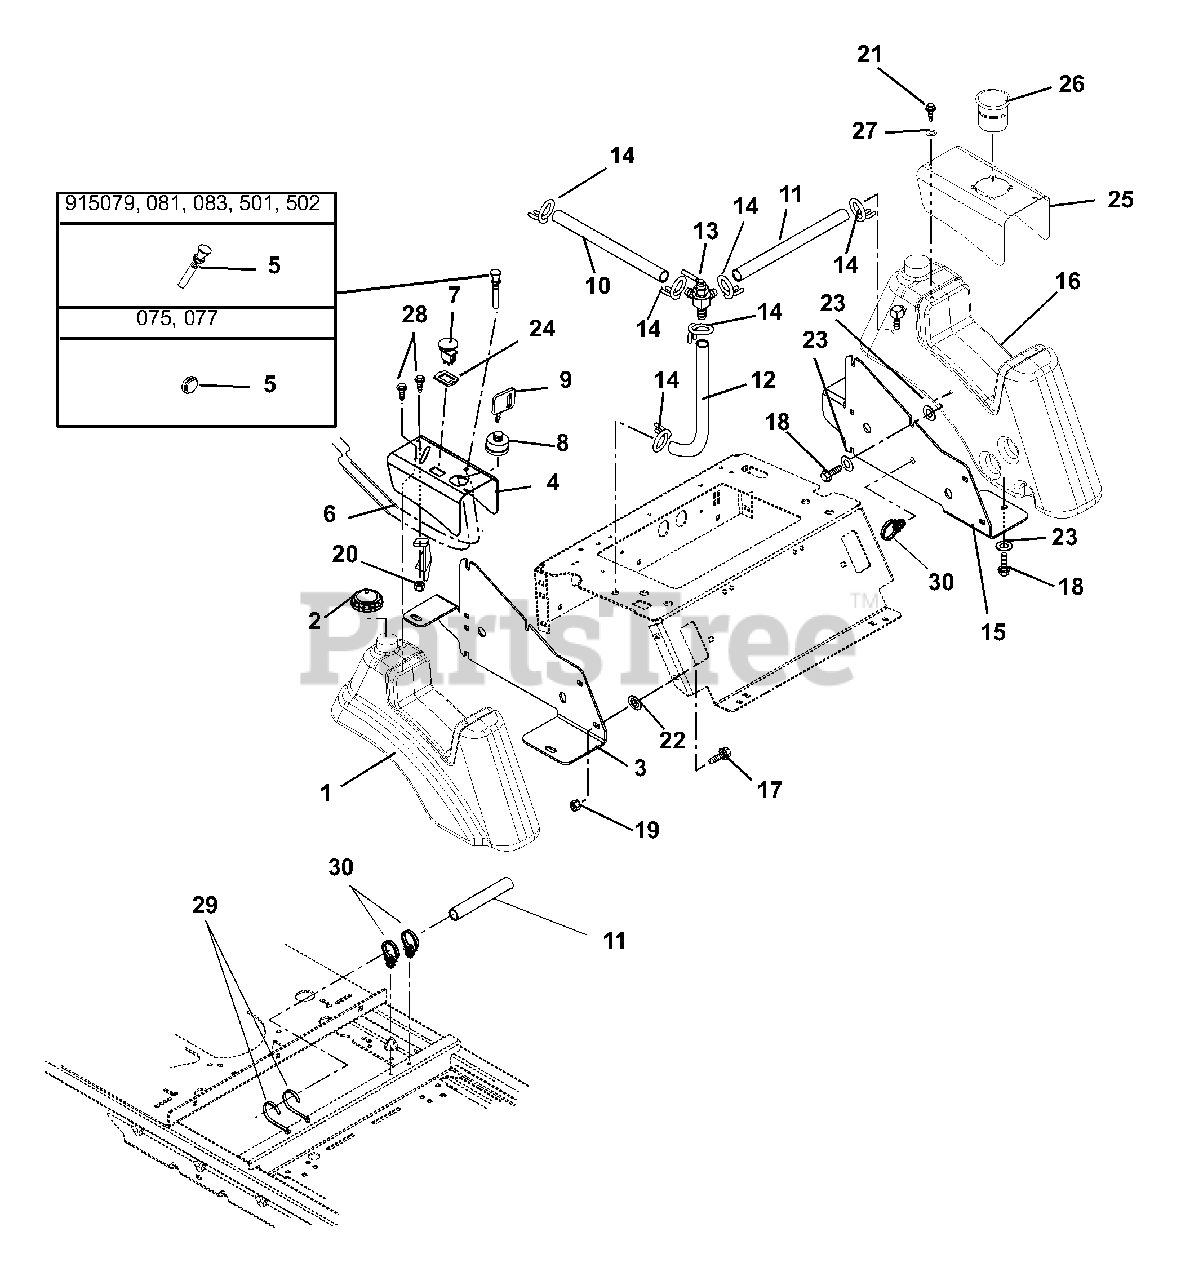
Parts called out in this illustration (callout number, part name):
1	FUEL TANK, RH
2	FUEL CAP
3	SEAT PLATE, RH
4	RH CONSOLE
5	CHOKE CABLE
6	THROTTLE CABLE
7	SWITCH, CLUTCH
8	KEY SWITCH
9	KEY -W/CAP
10	GAS LINE-BULK 1/4" I.D.
11	GAS LINE-BULK 1/4" I.D.
12	GAS LINE-BULK 1/4" I.D.
13	VALVE, FUEL
14	CLAMP-HOSE WIRE .490/.510X.116
15	SEAT PLATE, LH
16	FUEL TANK, LH
17	@BLT-RDHDSQNK .38-16X1.00 G5YZ
18	BLT-SERHFWH .312-18X.75 YWZC
19	@NUT-LK-NYL-FLG .38-16 YWZC
20	@NUT-LK-NYL 10-24 W/INSRT YWZC
21	SCR-MCH 10-24X3/8 SL HEX YWZC
22	RETAINER, .38 PUSH-ON
23	WSHR-FL-STL .328X1.0X.094 YWZC
24	SHIM,PTO SW (DELTA #972301)
25	LH CONSOLE
26	CUPHOLDER
27	WASHER, FENDER 3/16X3/4 YWZC
28	@SCR-MCH 10-24X.50 HWH YWZC
29	CABLE TIE, .18X8.5 50 LB PUSH
30	WIRE CLIP
